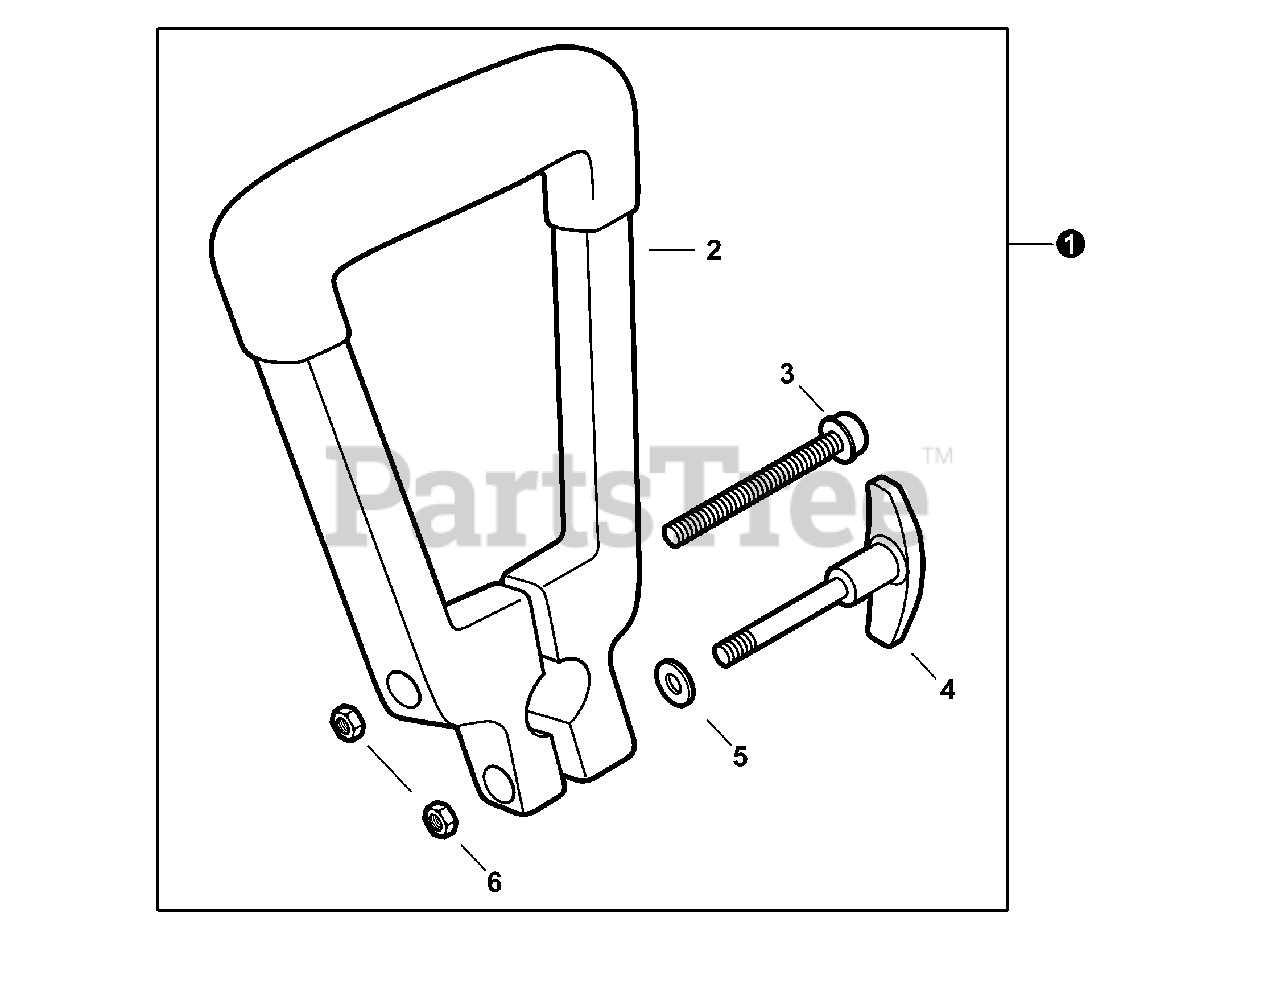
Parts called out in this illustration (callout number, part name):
1	HANDLE ASSY, FRONT
3	SCREW 6
4	KNOB, SCREW
5	WASHER 6
6	NUT, HEX M6
